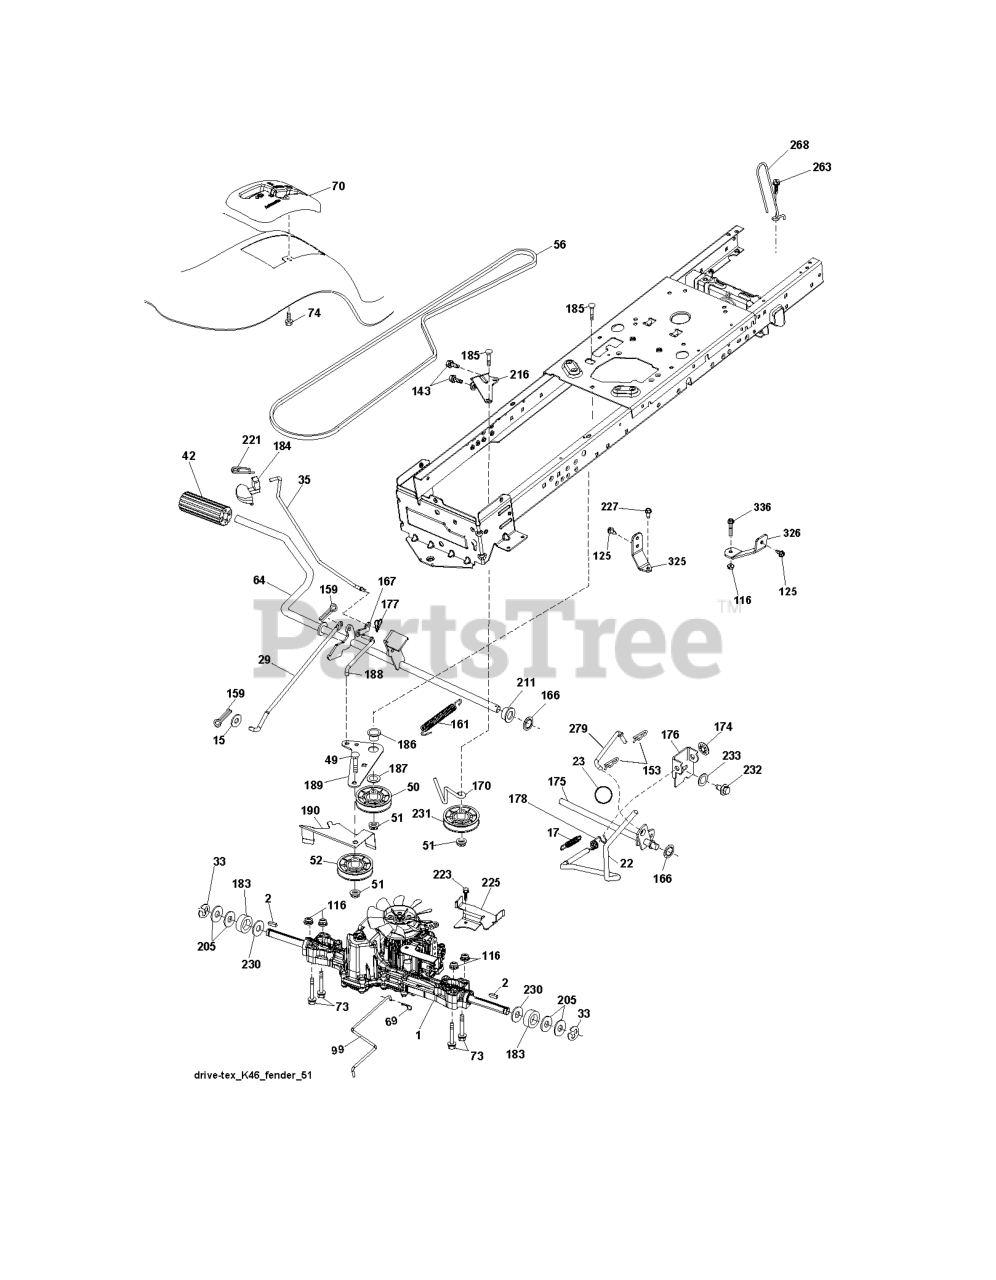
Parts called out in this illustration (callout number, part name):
1	BATTERY
2	BOLT.HEX.1/4.X.3/4.DICHROMATE
3	LOCKWASHER
6	NUT
7	PLASTIC TUBE
8	BATTERY TRAY T
9	HOSE CLAMP T
10	BOLT 1/4-20 X 7.5
11	HOLDDOWN, BATTERY, DASH MOUNT
12	NUT, PUSH NYLON 1/4" BATTERY
19	LOCKWASHER
20	NUT
21	HARNESS LIGHT SOCKET
24	CABLE, STARTER
25	CABLE, BATTERY
28	CABLE, GROUND
29	RP.SWITCH.PLUNGER.NC.GRAY
30	IGNITION SWITCH
31	NUT, IGNITION
32	COVER SWITCH KEY
33	KEY MLD GEN DELTA
39	SWITCH INTERLOCKT
41	SCREW
42	TERMINAL COVER
43	SOLINOID
46	HOUR METER T
47	Screw 10-24 x 1/2 Black
50	SWITCH PTO 3 PDT
51	FRAME RETAINING RING
53	SCREW **
54	Nut, Hex, Keps #10-32 UNF
61	LIGHT PACKAGE
62	BULB LIGHT T
81	RELAY.ASSY.T
